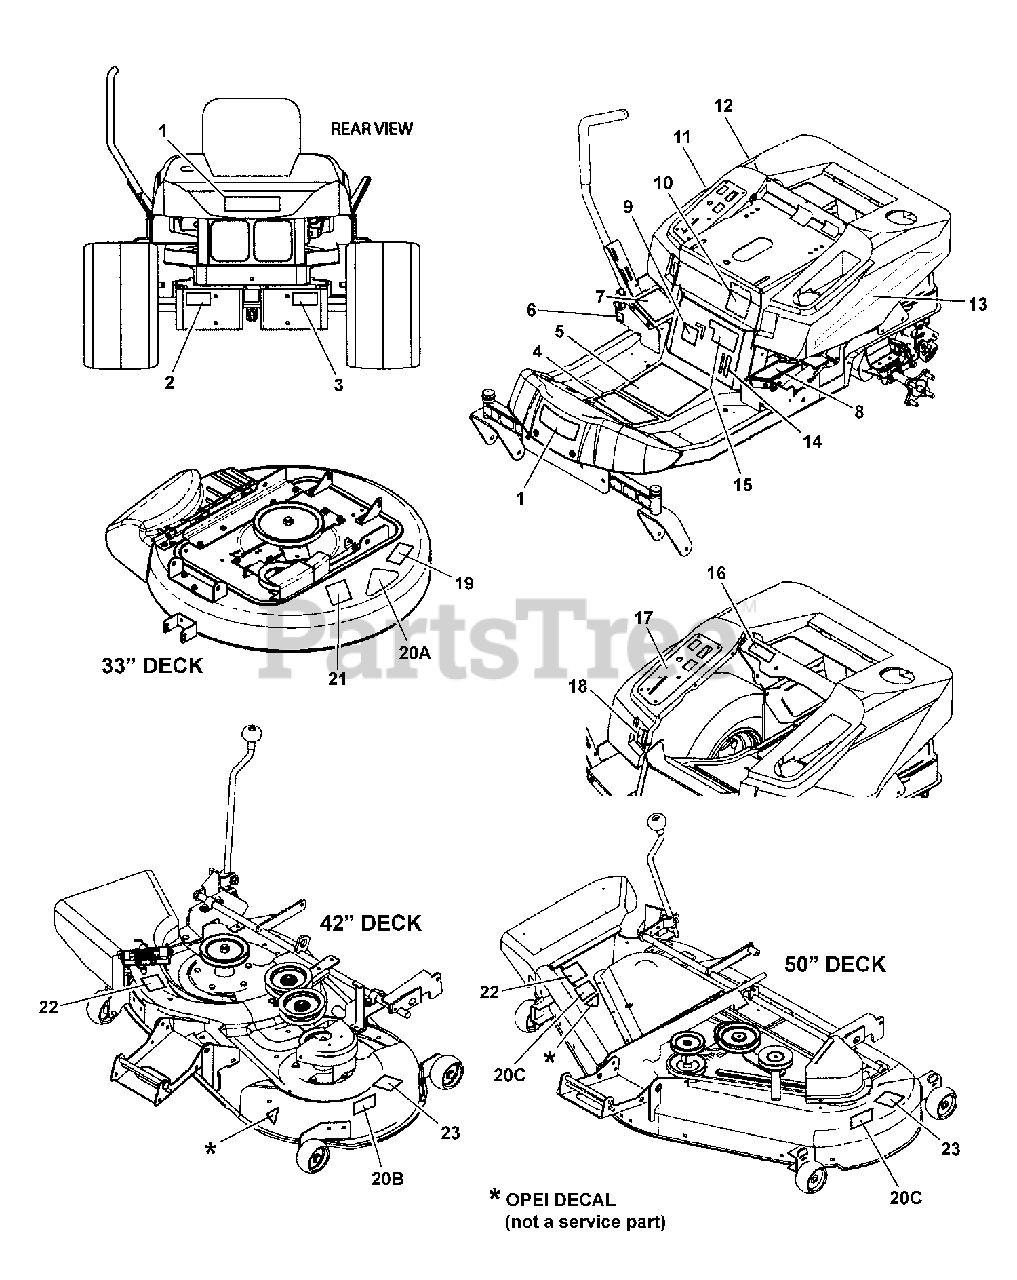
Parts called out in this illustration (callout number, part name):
1	DECAL, Simplicity Logo
2	DECAL, Caution Cut Hazard
3	DECAL, Transmission Release ZTS Export
4	DECAL, Handles Operation
5	DECAL, Operator Instructions
6	DECAL, Tracking Adjustment ZT 7000
7	DECAL, RH Handle
8	DECAL- LH Handle Control ZTS 7500
9	DECAL, Parking Brake, ZT
10	DECAL, Belt/Blade 33" ZT
10	DECAL, Belt/Blade ZT
11	DECAL, Hot Surfaces
12	DECAL, Simplicity-RH Stripe ZT 2007
13	DECAL, Simplicity-LH Stripe ZT 2007
14	DECAL, Height-Of-Cut
15	DECAL, Axion 18.5 HP Simplicity ZT
15	DECAL, Axion 21 HP Simplicity ZT
15	DECAL, Axion 26 HP Simplicity ZT
16	DECAL, Do Not Remove Foam Around Engine
17	DECAL, Instrument Panel SEARS ZTS 7500
18	DECAL, Mower Cutting Height ZTS 7500
19	DECAL, Danger Do Not Operate w/o Deflector
20A	DECAL, 33" Hi-Vac
20B	DECAL, 42" 2006 Silver/Black
20C	DECAL, 50" Silver on Black w/Stripe
21	DECAL, Warning/Danger
22	DECAL, Danger Do Not Operate w/o Deflector
23	DECAL, Danger Do Not Put Hands/Feet in Mower
